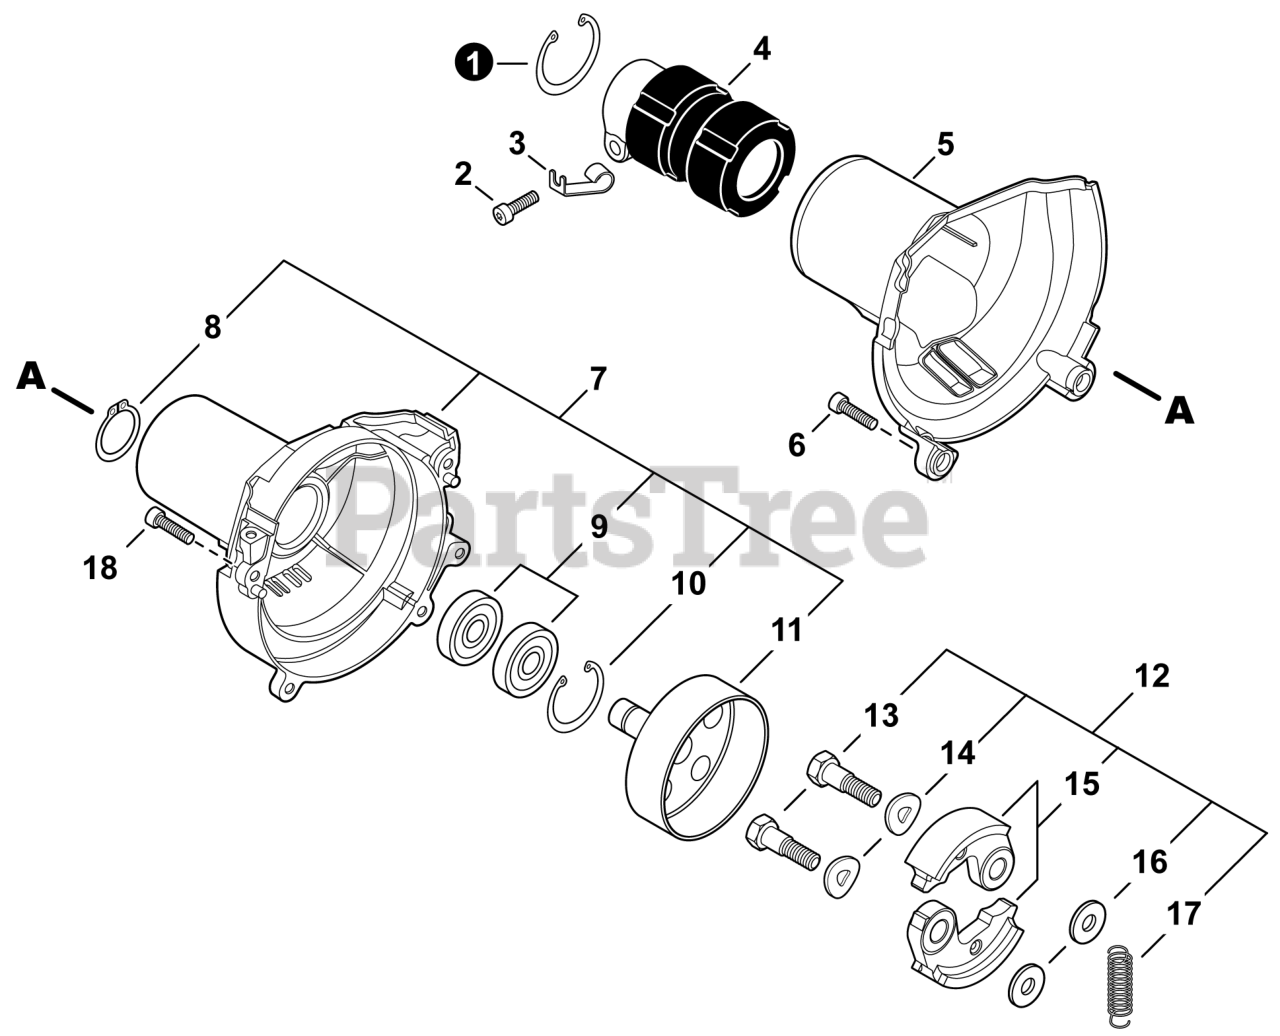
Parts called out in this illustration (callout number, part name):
1	RING, SNAP 42
2	BOLT, TORX 5x25
3	CLIP, CABLE
4	HOLDER, MAIN PIPE
5	PROTECTOR, FAN COVER
6	BOLT, TORX 5x20
7	COVER ASSY, FAN
8	RING, SNAP 12
9	BEARING, BALL 6001
10	RING, SNAP 28
11	DRUM, CLUTCH
12	CLUTCH ASSY
13	BOLT, CLUTCH 8x7.9xM6
14	WASHER, SPRING 8.5x16x0.5
15	SHOE, CLUTCH
16	WASHER 6.2x19x1.0
17	SPRING, CLUTCH
18	BOLT, TORX 5x16
